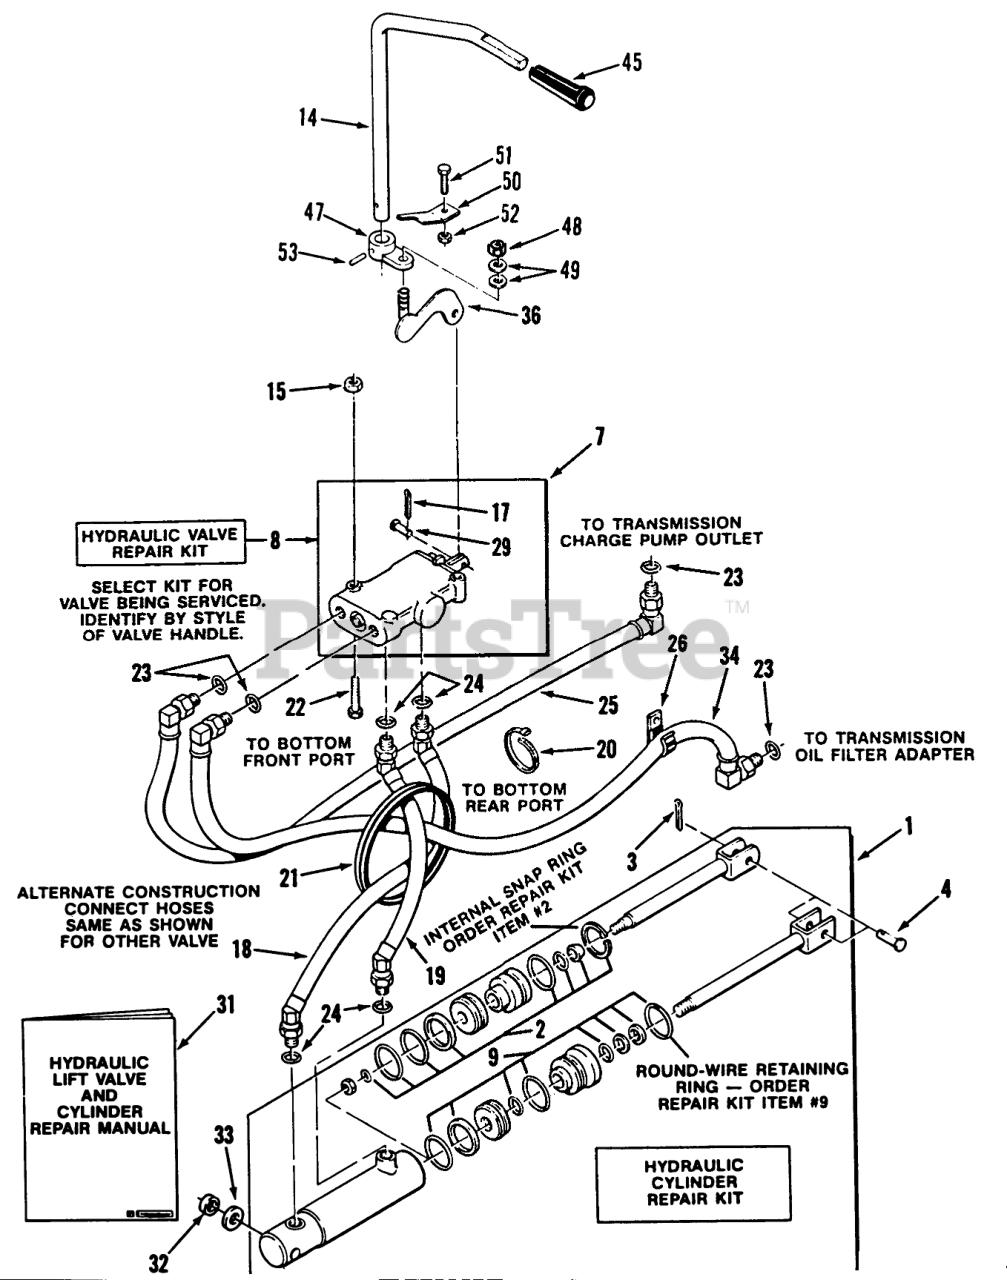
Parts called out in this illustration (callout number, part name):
1	ASS'Y-CYLINDER
2	S/A O-RING&GASKET AS
4	CLEVIS PIN
7	ASS'Y-VALVE
8	S/A 110068 VALVE
9	S/A 108872 HYD CYL
14	ROD-LIFT CONTROL
15	Nut
17	Cotter Pin
18	Hose ASM-Hydraulic
19	Hose ASM-Hydraulic
20	PLASTIC TIE
21	GROMMET
22	Bolt 1/4-20 x 2
23	0-Ring
24	O RING
25	ASSY HOSE HYDRAULIC
26	CLIP
29	Pin
31	Repair Manual
32	SPACER
33	WASHER
34	ASSY HYD HOSE
36	WLDMT-LIFT BAR
45	KNOB-HYDRAULIC LIFT
47	ARM-CONTROL
48	Nut
49	WASHER 5/16 SAE
50	BRACKET-CONTROL R B
51	Bolt
52	Nut
53	SPIROL PIN 7/32X7/8
